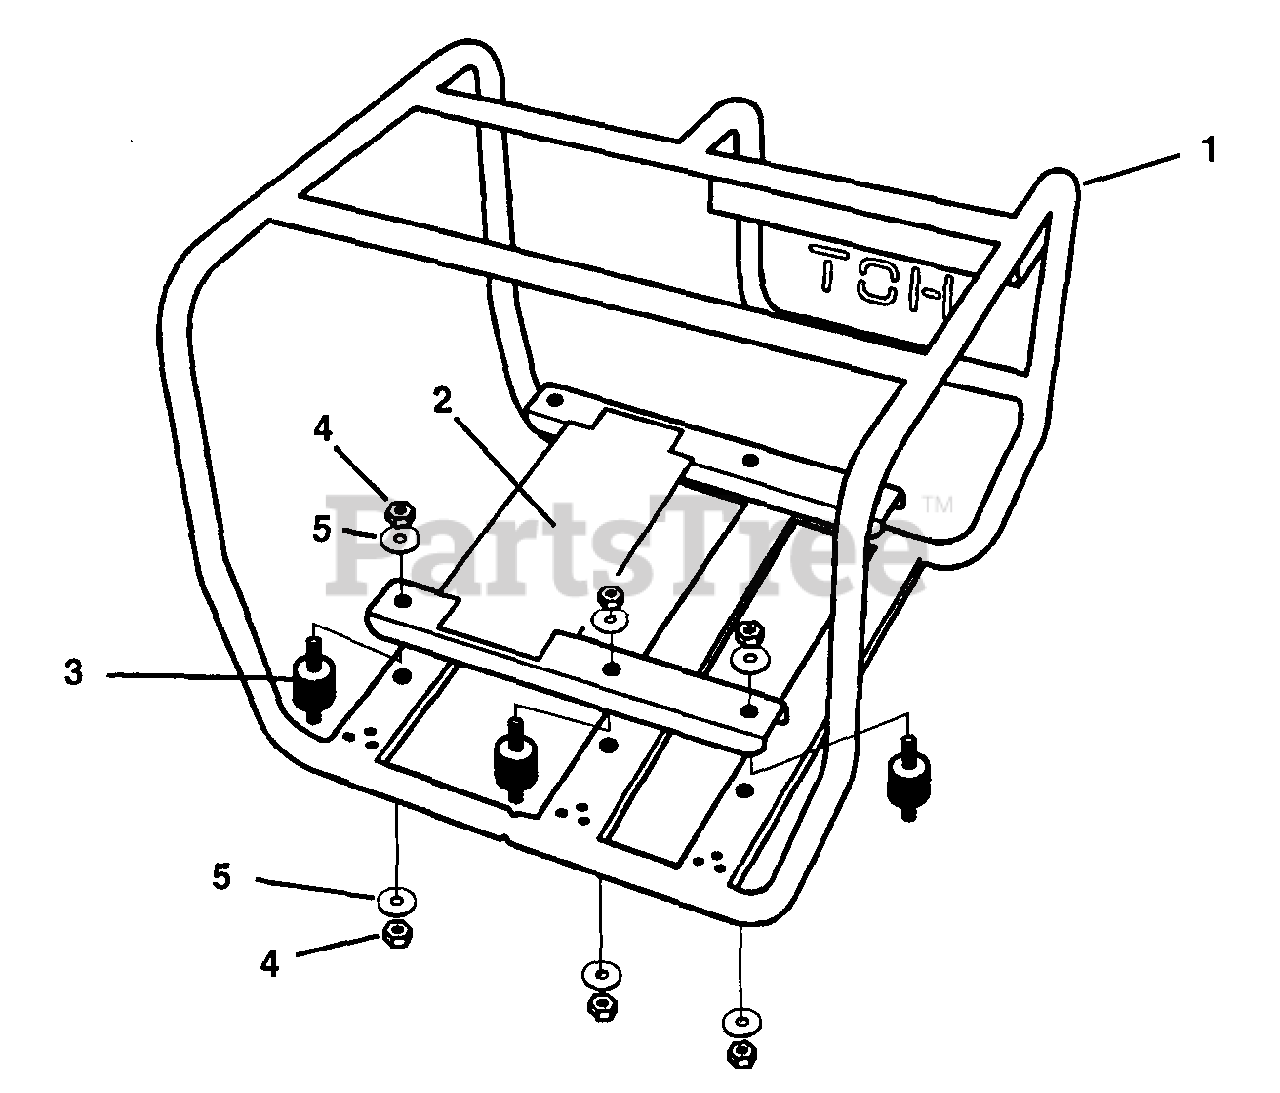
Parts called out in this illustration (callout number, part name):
1	ROLL CAGE
2	ENGINE SUPPORT
3	ISOLATOR
4	NUT (5/16-18)
5	WASHER (5/16)
